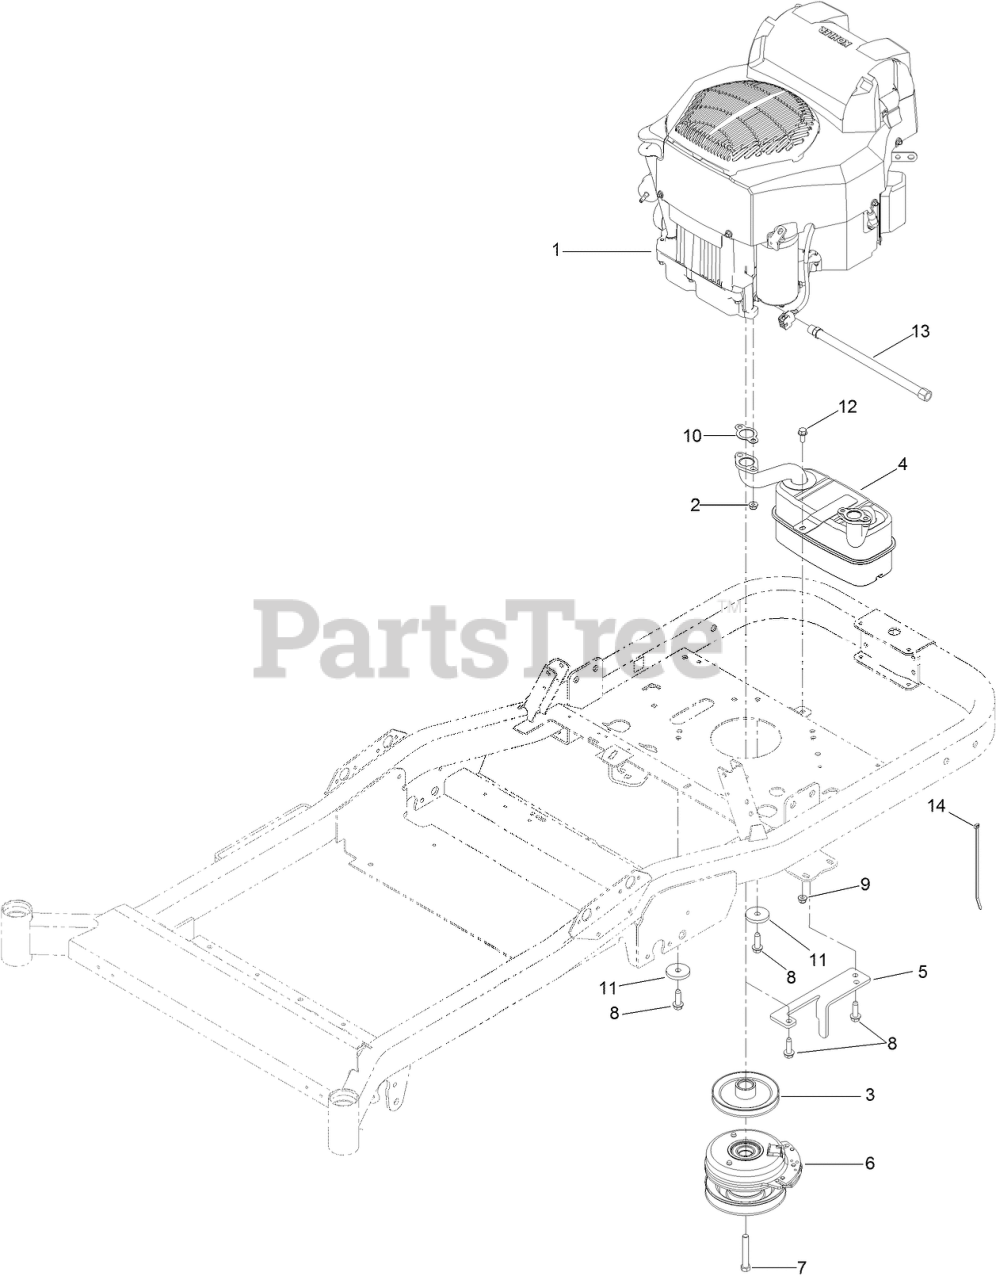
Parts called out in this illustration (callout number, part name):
2	NUT-LOCKING, EXHAUST
3	PULLEY-ENGINE
4	MUFFLER
5	BRACKET-STOP, PTO
6	CLUTCH-PTO
7	SCREW-HH
8	SCREW-TAPTITE
9	NUT-HF, NI
10	GASKET-EXHAUST
11	WASHER-PLAIN
12	SCREW-HHF
13	HOSE-DRAIN, OIL
14	TIE-CABLE
